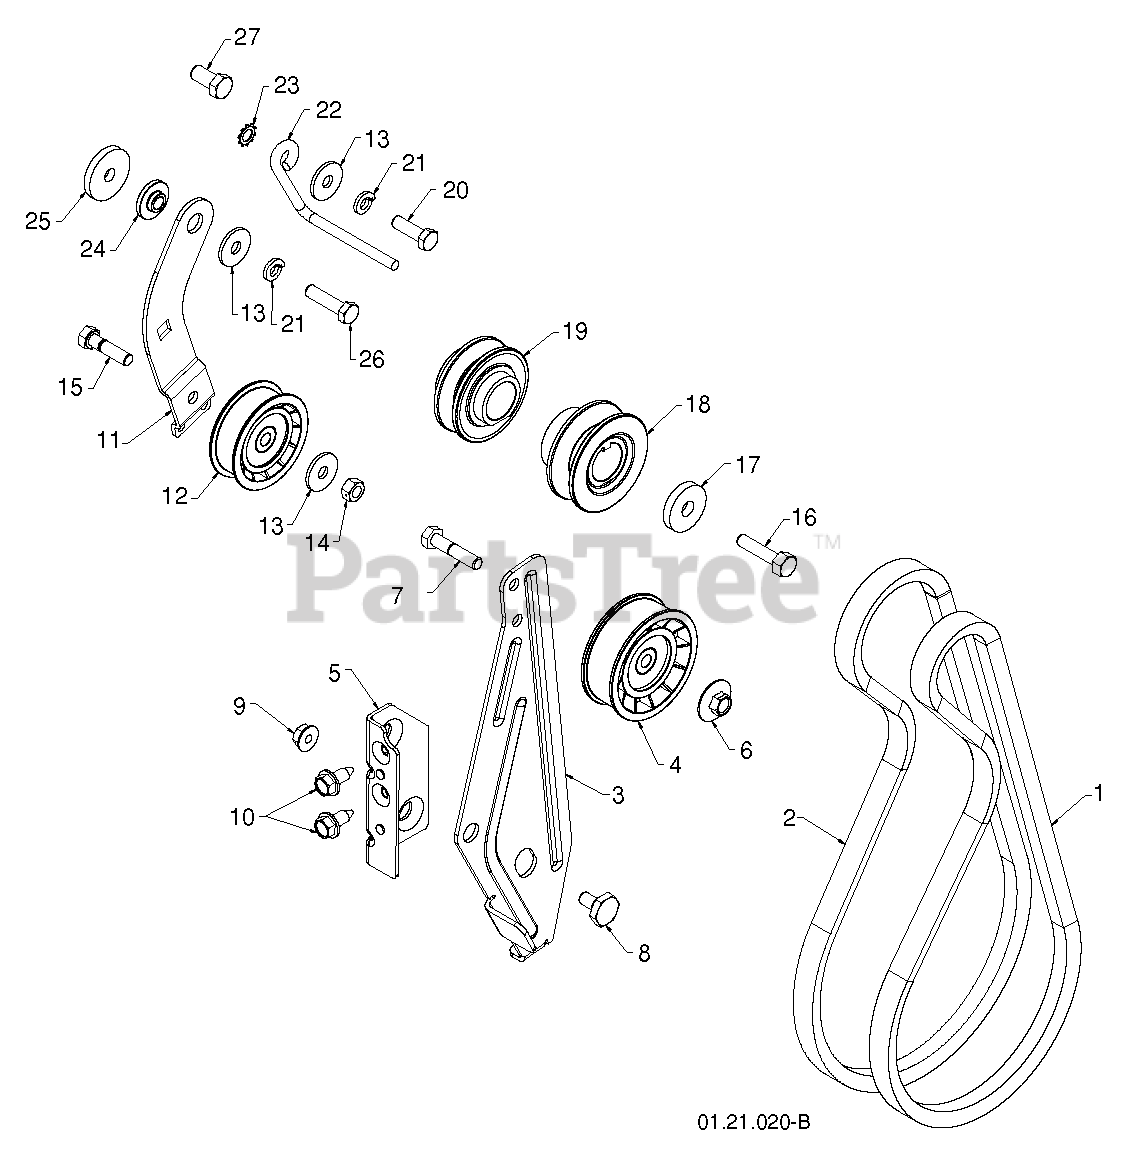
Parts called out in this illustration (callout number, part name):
1	V-BELT.IMPELLER
2	TRACTION BELT
3	RP ARM.IDLER.BRAKE.
4	PULLEY.W/SPACER.2.75
5	RP BRACKET.IDLER.PIVOT
6	NUT.FLANGE.HEX.5/16X18.BLACK
7	HEX BOLT
8	BOLT.SHOULDER.1/2X12
9	NUT.LOCK.5/16-18
10	BOLT.5/16HEX.WHS.HD
11	ARM.ASM.TRACTION.IDLER
12	PULLEY.W/SPACER.2.25
13	STEEL WASHER
14	NUT.71038.31-18.HEX.NYLOCK
15	BOLT.5/16-18X1-1/4 FULL.THREAD
16	SCREW, HEX HD 3/8-24 X 1-3/8
17	WASHER.400X1.25X5.
18	PULLEY ENG IMPELLER
19	PULLEY.ASM.ENG.TRACTION.1.00
21	LOCKWASHER
22	Belt Guide, RH
24	BUSHING, IDLER PIVOT
25	WASHER.400X1.25X5.
26	CAPSCREW.HEXHD.5/16X1.25.
27	SCREW.3/8-16 X .750
